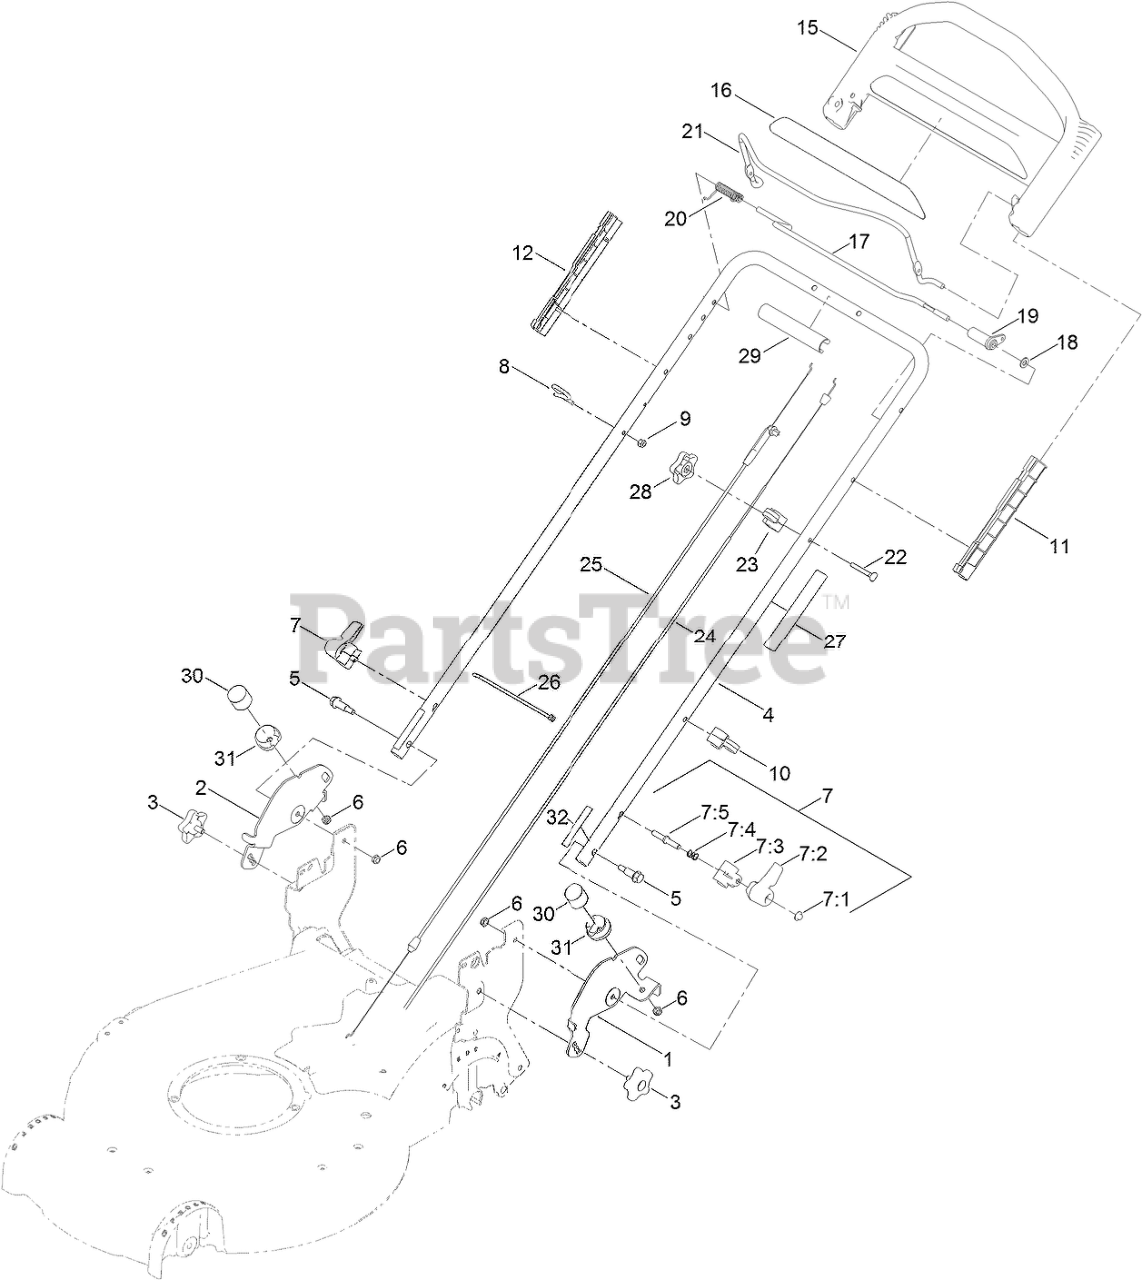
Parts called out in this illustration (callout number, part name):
1	BRACKET-FLOAT, LH
2	BRACKET-FLOAT, RH
3	KNOB-HANDLE
4	HANDLE-UPPER
5	BOLT-SHOULDER
6	NUT-LOCK, NI
7	QUICK RELEASE ASM
7:2	LEVER
7:3	ANCHOR-SPRING
7:4	SPRING-COMPRESSION
7:5	ROD-RELEASE
8	GUIDE-ROPE
9	NUT-LOCK, NI
10	GUIDE-CABLE
11	GUIDE-LH
12	GUIDE-RH
15	HANDLE-CONTROL
17	BAR-CONTROL, TRACTION
18	WASHER-PLAIN
19	LEVER-TRACTION
21	BAIL-BRAKE
22	SCREW
23	ANCHOR-CABLE
24	CABLE-TRACTION
25	CABLE-BRAKE
26	TIE-CABLE
27	DECAL-TRACTION, ADJUST
28	KNOB-HANDLE, LOCKING
29	HANDLE-COVER
30	BUMPER-RUBBER
31	COVER-BUMPER
32	DECAL-ISOFLEX
